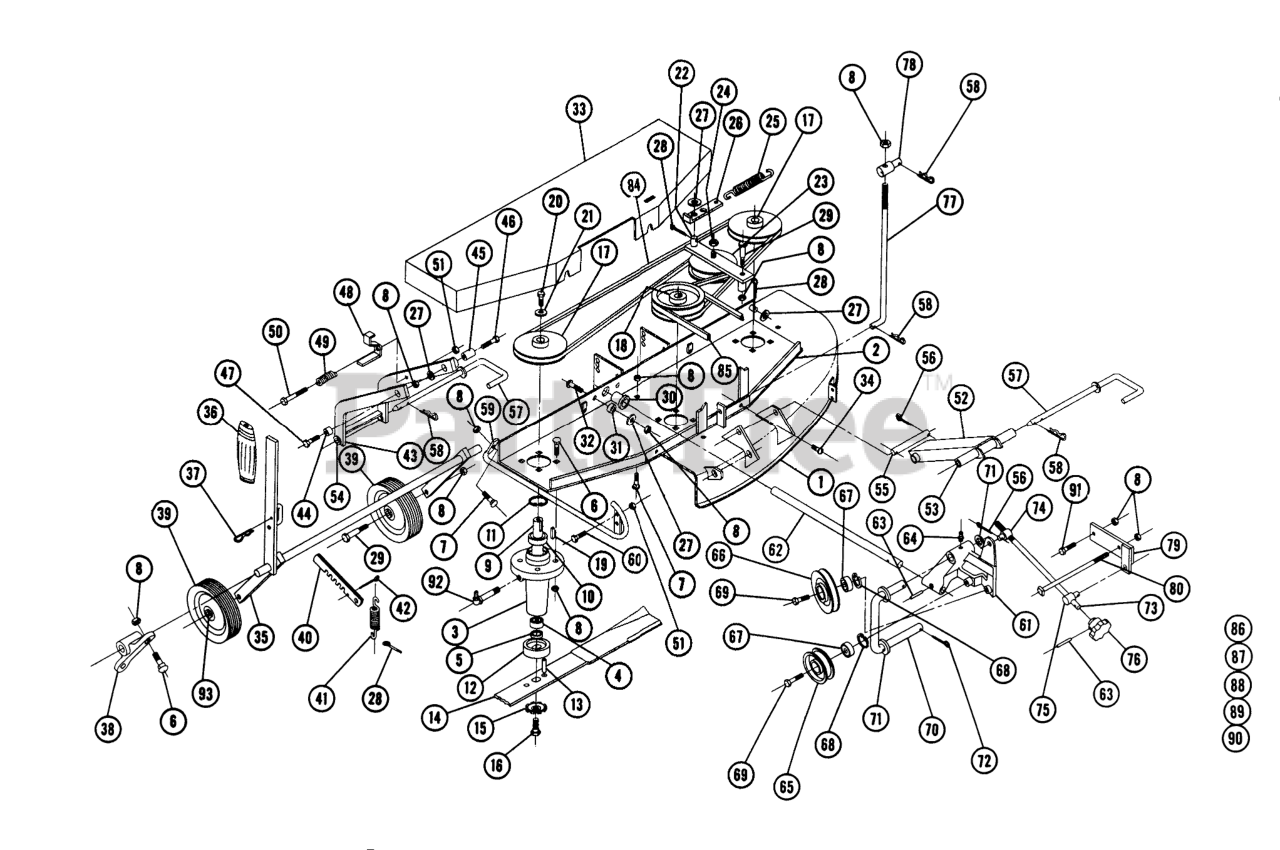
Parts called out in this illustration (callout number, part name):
1	Ass-y. Deck
2	Ass-y. Channel-Deck Support
3	Housing
4	NEEDLE BEARING
5	Seal
6	Bolt 3/8-16 x 1
7	Bolt-3/8-16 x 3/4
9	SPINDLE SHAFT
10	Ball
11	Snap-Ring 1 5/8 Bore
12	SPINDLE CUP
13	SPIROL ROLL PIN
14	Blade
15	WASHER
16	Bolt-Nylock 3/8-16 x 7/8
17	Pulley
18	Pulley-Double Groove
19	KEY-STRAIGHT
20	Bolt-Nylock 3/8-16 x 7/8
21	WASHER
22	Bolt-Shoulder
23	Pulley-Idler
24	Locknut-1/2-13
25	Spring
26	Plate Spring Adj.
27	Washer
28	Cotter Pin
29	BOLT-SHOULDER
30	Bushing
31	SPACER
32	Bolt-Truss HD. 3/8-16 x 7/8
33	Cover
34	H.H.C.S. 1/4-20 x 1/2
35	Ass-y. Gage Wheel Adj. Rod
36	Grip
37	Hairpin
38	Bearing-Cast Iron
39	Wheel
40	Ass-y. Arm-Gage Wheel
41	Spring
42	Cotter Pin 1/8 x 1/2
43	Ass-y Trip Lever
44	Spacer
45	Spacer
46	Bolt, 3/8 16 x 2
47	Bolt 3/8-16 x 1
48	latch-Lift
49	SPRING-COMPRESSION
50	Bolt-Hex 3/8-16 x 2
51	Nut-Nylok
52	Ass-y. Lift Link-Front
53	Bushing
54	FLANGED BUSHING
55	Pin-Front Link-Lower
56	Cotter Pin
57	Ass-y. Pin Lift Link
58	Hairpin
59	Washer
60	Bolt, 5/16-18 X 7/8
61	Bracket-Idler Mtg.
62	Rod-Leveling
63	PIN-ROLL
64	Zerk
65	Pulley Idler
66	PULLEY IDLER
67	BEARING
68	Snap Ring 1 3/8 Bore
69	Bolt 3/8-16 x 1 1/4 Nylok
70	Shaft-Idler Support
71	WASHER
72	Cotter Pin 5/32 x 1 1/4
73	Rod-Drive Adj.
74	Trunnion
75	Stud
76	Knob
77	Rod
78	LIFT STUD
79	Ass-y.-Belt Adj. Bracket
80	Bolt-Hex. 3/8-16 x 8 1/2
81	Housing
82	OIL SEAL
83	Bearing-Needle
84	V-BELT
85	V BELT
86	Wrench 1/8 Hex Allen
87	Decal
88	DECAL
89	Decal
90	Decal Belt Installation
91	Bolt 3/8-16 x 1
92	Fitting-Grease
93	Bushing-Wheel
